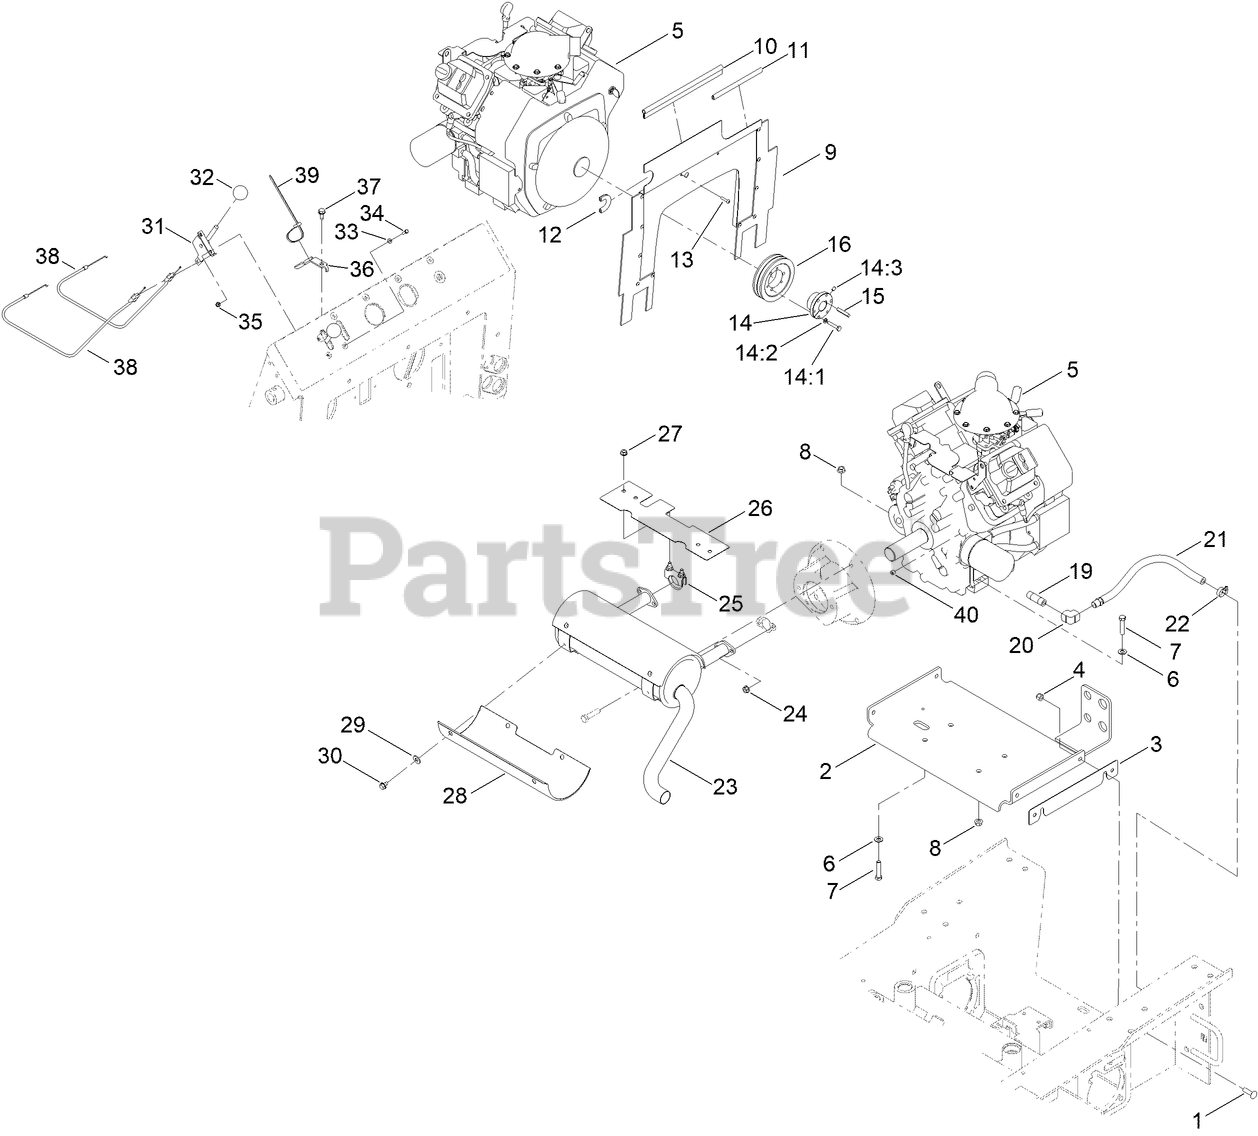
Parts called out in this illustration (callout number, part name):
1	SCREW-CARR
2	PLATE-MOUNTING, ENGINE
3	SHIM-STRAP
4	NUT-LOCK, NI
6	WASHER-PLAIN
7	SCREW-HH
8	NUT-HF
9	BAFFLE-ENGINE
10	STRIP-SEAL, 10.5 INCH
11	SEAL-STRIP, 6.5 INCH
12	SEAL-STRIP, 3 INCH
13	SCREW-PPH
14	BUSHING
14:1	SCREW-HH
14:2	WASHER-LOCK
14:3	SCREW-SET, HSH
15	KEY-SQUARE
16	PULLEY
19	NIPPLE
20	ELBOW-90 DEG
21	OIL HOSE ASM
22	CLAMP-HOSE
23	MUFFLER
24	NUT-HF
25	Clamp-Muffler
26	SHIELD-MANIFOLD
27	NUT-HF
28	SHIELD-MUFFLER
29	WASHER-FLAT
30	SCREW
31	LEVER-CONTROL
33	WASHER-FLAT
35	NUT-KEPS
36	GUIDE-CABLE
37	SCREW-THD ROLL, HWH
38	CABLE-THROTTLE/CHOKE
39	TIE-CABLE
40	PLUG-PIPE
